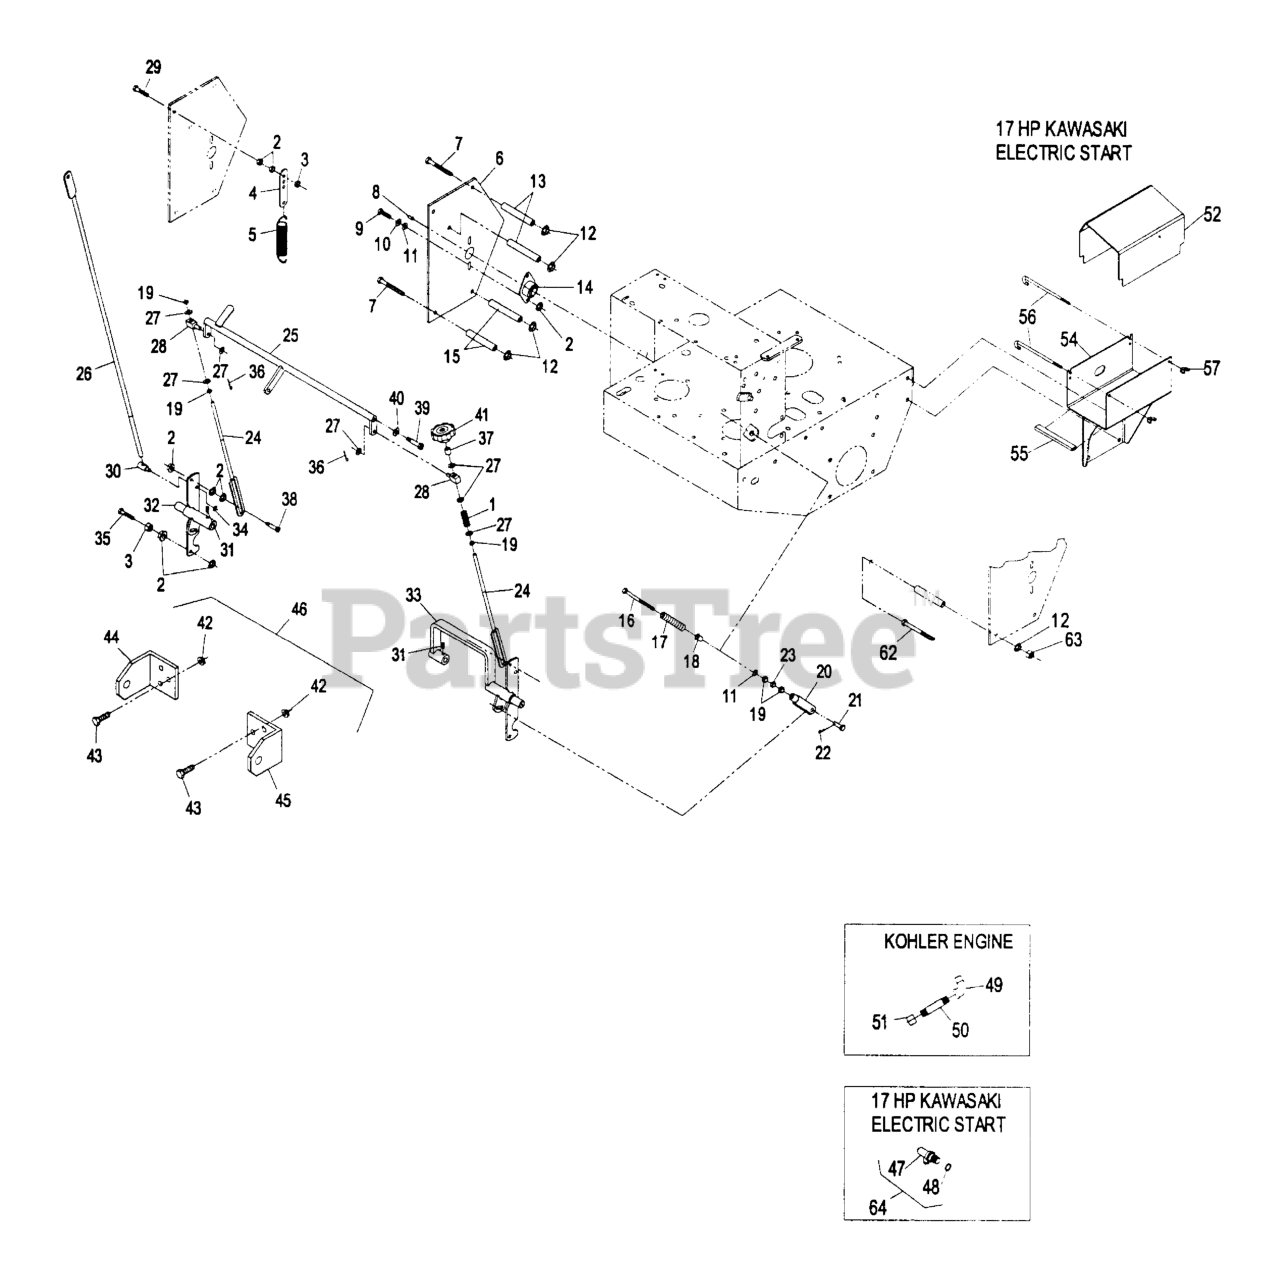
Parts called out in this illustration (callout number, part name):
1	SPRING-COMPRESSION
4	TAB-SPRING, EXTENSION
5	SPRING-EXTENSION
10	WASHER-LOCK
13	SPACER-SHIELD
14	BEARING-FLANGE, SIDE
15	SPACER-SHIELD
16	BOLT-RETURN, NEUTRAL
17	SPRING-RETURN, NEUTRAL
18	BUSHING-FLANGED
20	YOKE-ADJUSTABLE
21	PIN-CLEVIS
22	PIN-COTTER
24	LINK-CONTROL, SPEED
25	CRANK-CONTROL, SPEED
26	ROD-LEVER, DRIVE
29	BOLT-TAP, HH
31	SCREW-SET
38	SCREW-HH
39	SCREW-HSH
41	KNOB-TRACKING
45	BRACKET,SULKY RH
46	Sulky Kit
49	FITTING-ELBOW-90
50	NIPPLE
51	CAP-HEX
53	Battery - 12v Mnfld
55	TRIM-LOK
56	BOLT - HOLD DOWN
57	WINGNUT
60	INSULATOR, BATTERY -
61	CABLE-BATTERY, NEGATIVE
64	KIT, OIL DRAIN VALVE
